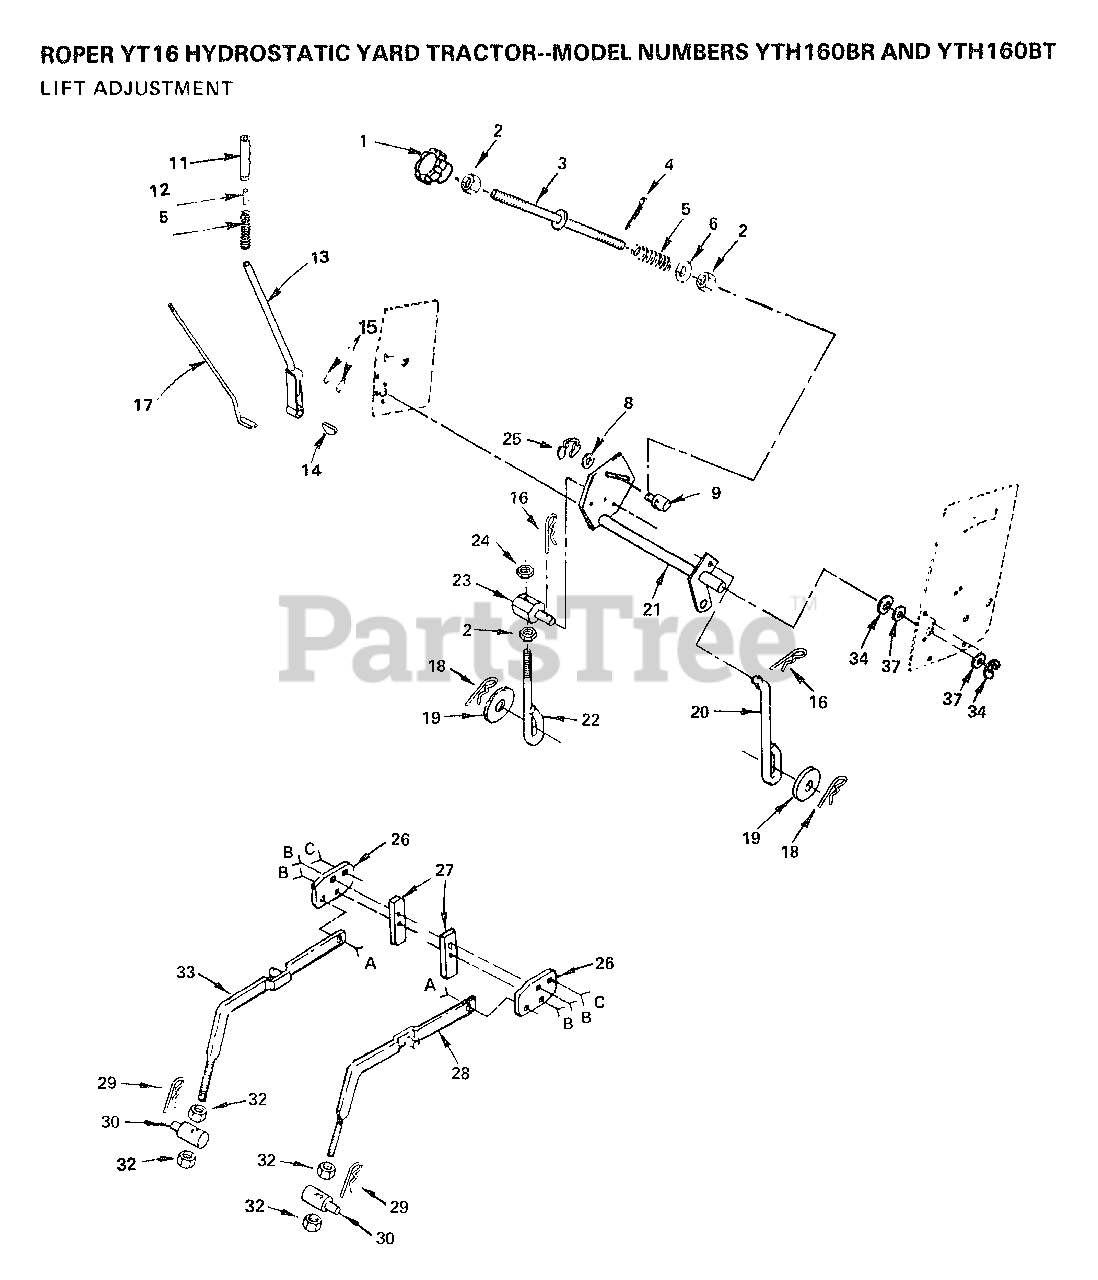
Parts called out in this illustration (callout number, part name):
2	NUT.HEX.3/8-16UNC
3	ROD ADJUST LT
5	SPRING T
6	WASHER
8	WASHER
11	GRIP
13	LEVER ASSY LT
17	ROD ASSY-LEVER LT
20	LIFT LINK LT
22	LINK LIFT LT
25	KLIP RING
26	"BRACKET, SUSPE T"
29	SPRING H
32	NUT
34	RING
37	WASHER
